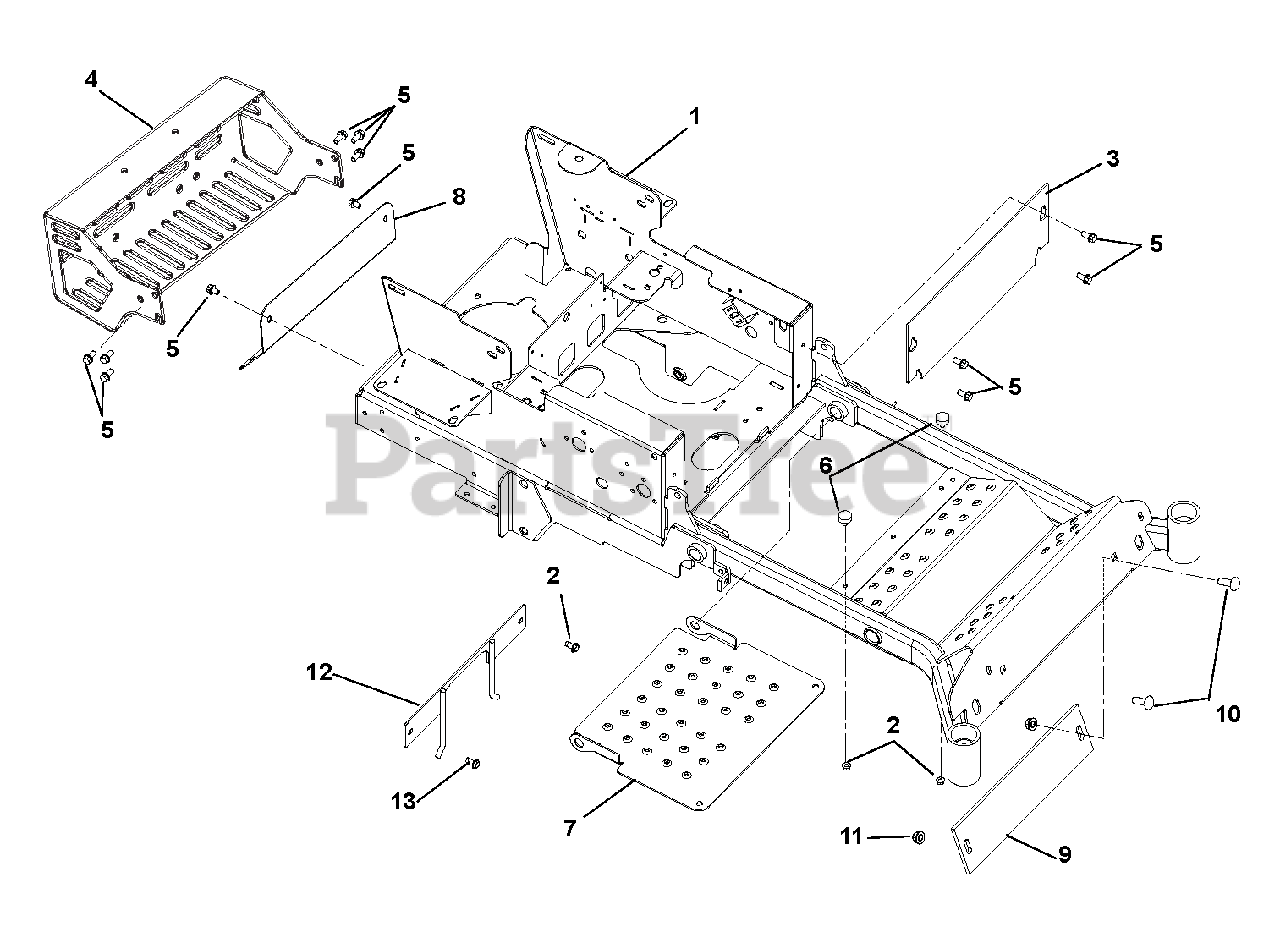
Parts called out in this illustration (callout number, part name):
1	WLDMT, 48" HD FRAME
2	@NUT-SPNLK-FLG .312-18 YWZC
3	PLATE, KICK
4	BUMPER, ARIENS MAX ZOOM
5	@SCR-TAP .38-16X.75 HWH TR YWZ
6	BUMPER, RUBBER
7	PANEL, INSPECTION
8	BRKT, HEAT SHIELD - MUFFLER
9	COUNTERWEIGHT, CZ FRONT-BLACK
10	BLT-RDHDSQNK .50-13X2.25 G5YZ
11	@NUT-LK-NYL-FLG .50-13 YWZC
12	PTO BELT FINGER WLDMT - BLK
13	@SCR-TAP .38-16X.75 HWH TR YWZ
